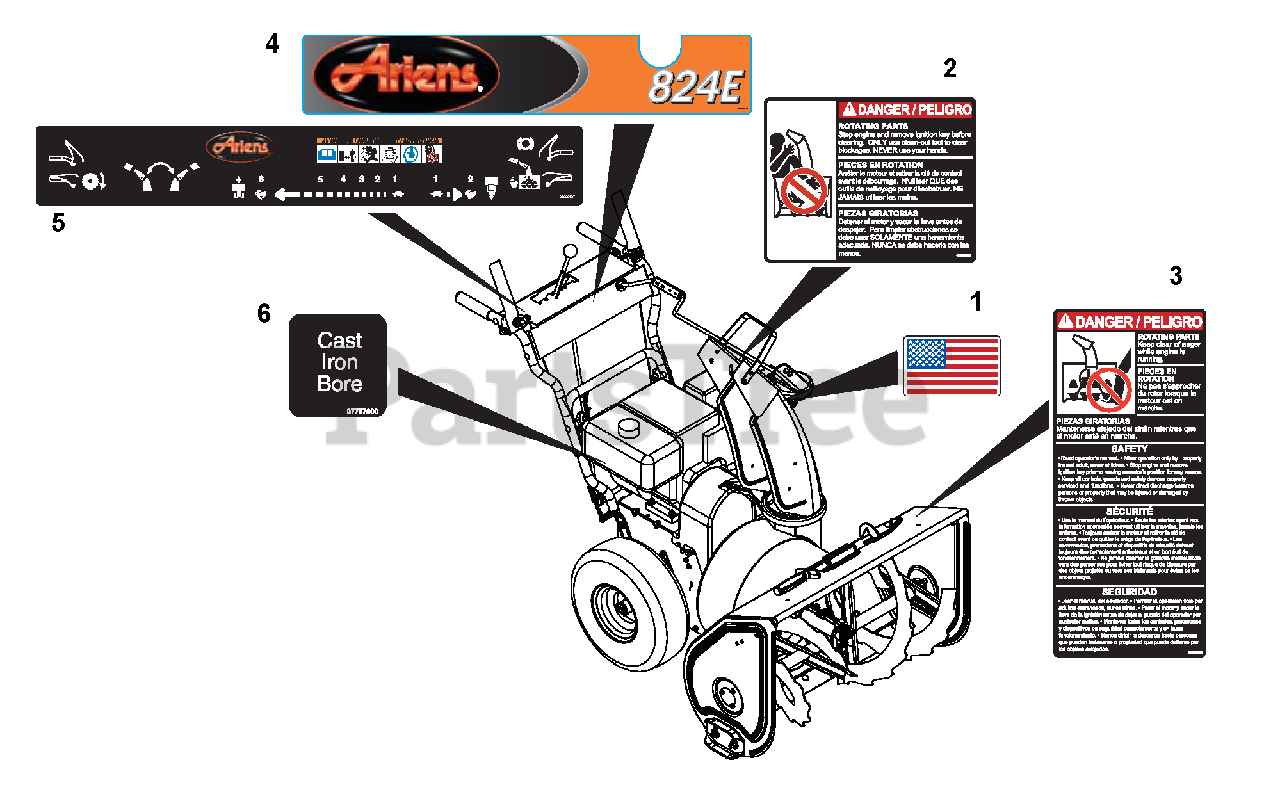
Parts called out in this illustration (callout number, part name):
1	DECAL, AMERICAN FLAG
2	DECAL, DANGER - ROT. PARTS
3	DECAL, DANGER
4	DECAL,ST824E
5	DECAL, CONTROL, COMPACT/DELUXE
6	DECAL - CAST IRON BORE
